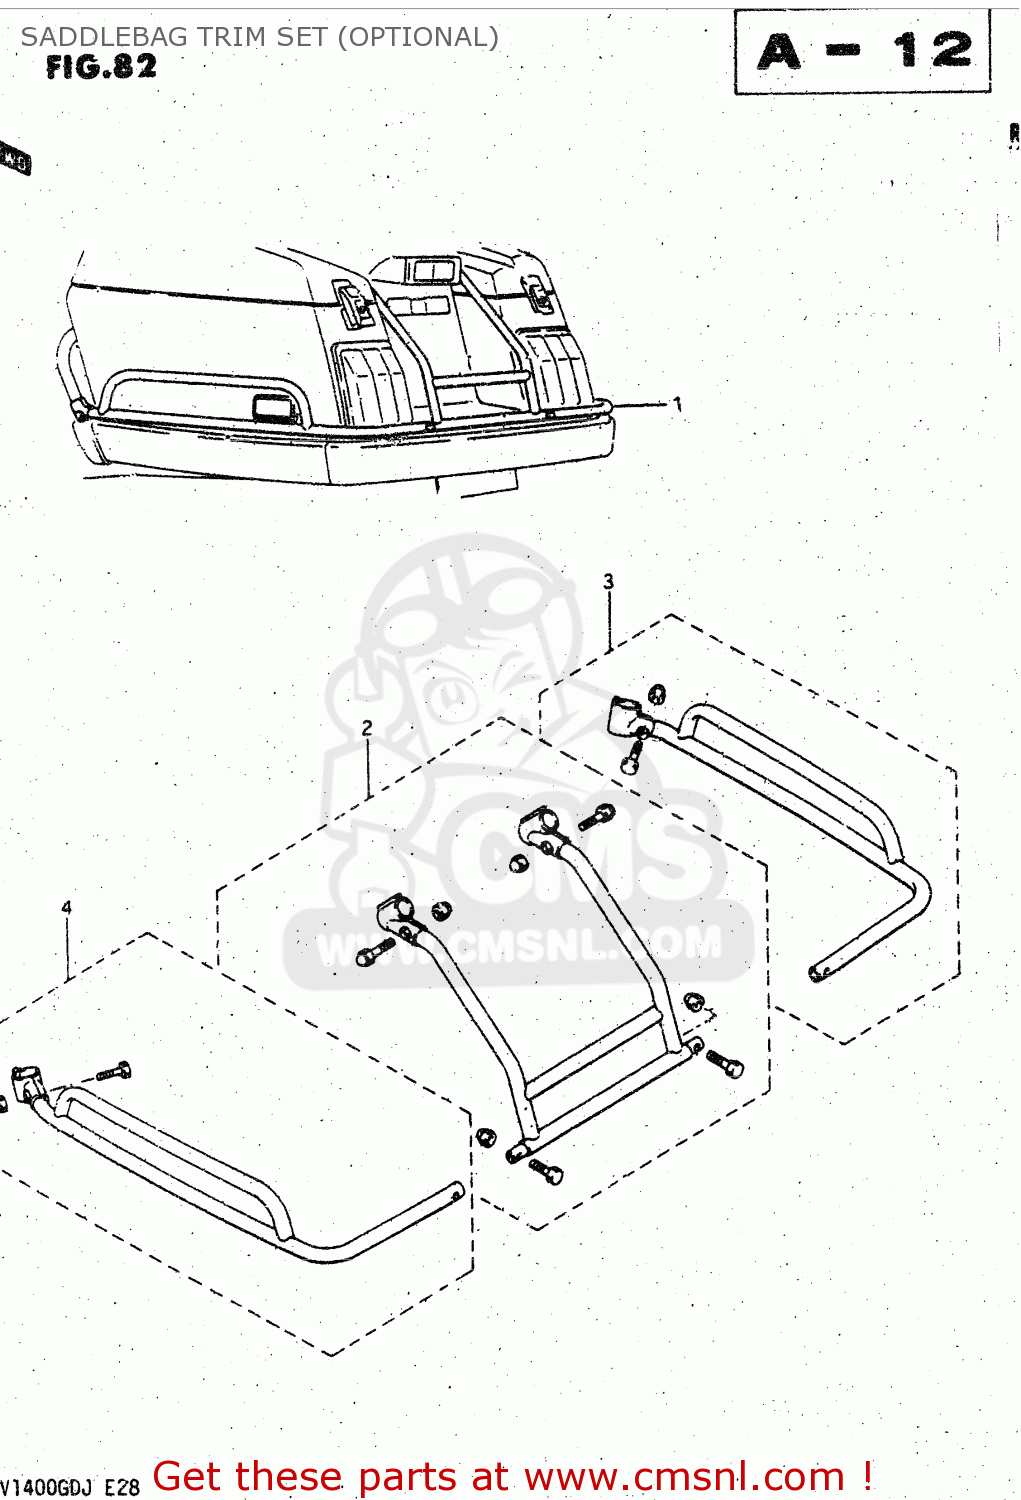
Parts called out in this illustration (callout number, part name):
1	TRIM SET, SADDLEBAG
2	TRIM, SADDLEBAG CENTER
3	TRIM, SADDLEBAG RH
4	TRIM, SADDLEBAG LH
